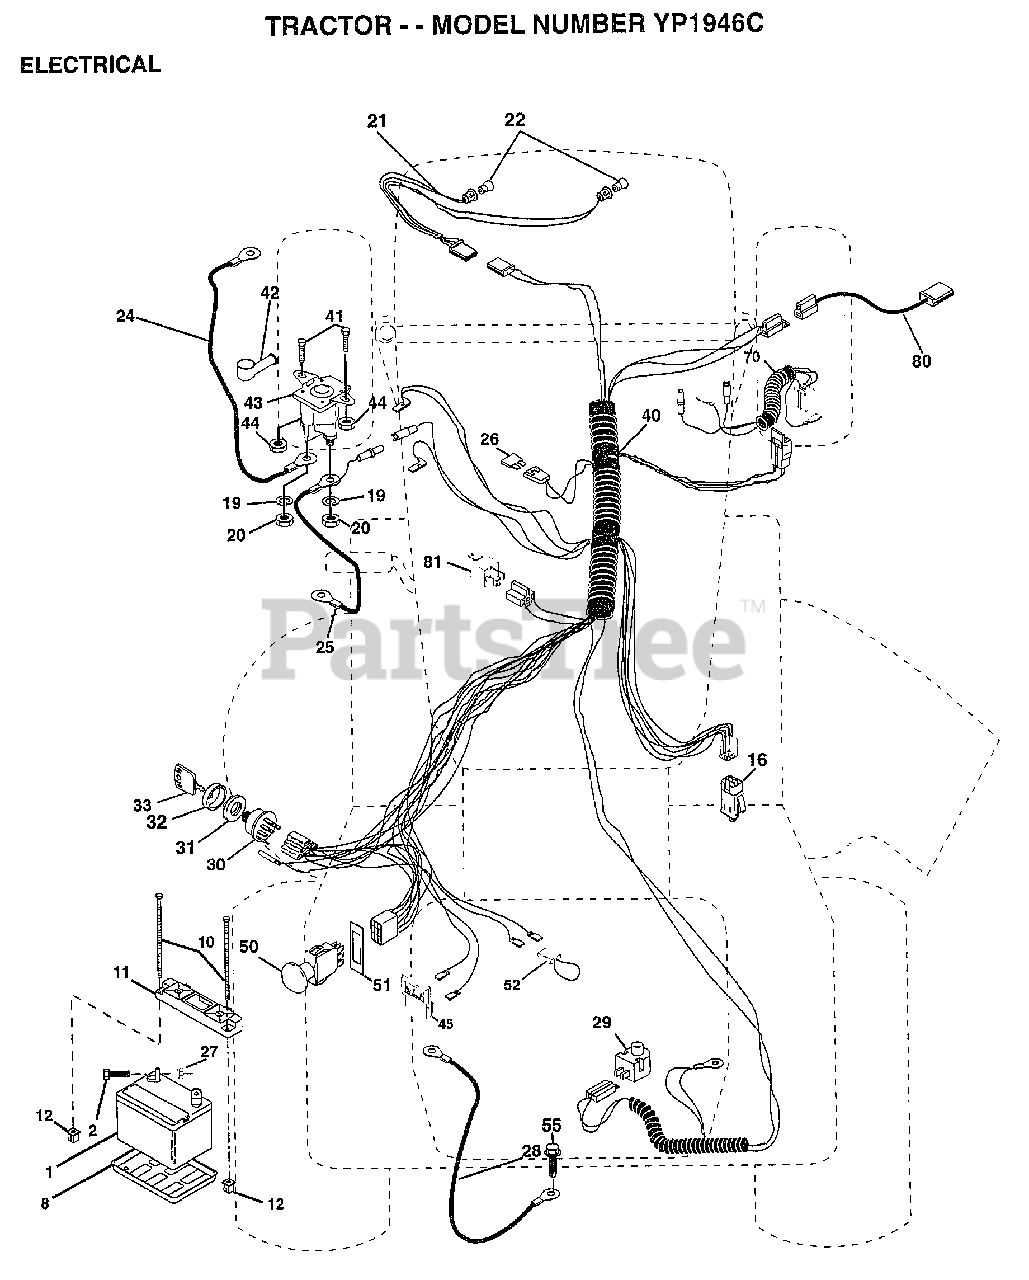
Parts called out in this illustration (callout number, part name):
2	BOLT LT
8	"TRAY T, BATTERY"
11	HOLDDOWN BATTERY
16	SWITCH INTERLOCK
20	NUT
21	HARNESS.ASM.LIGHT W/4152J
22	HEADLAMP BULB
24	"CABLE T, BATTERY"
25	CABLE.6GA.22W/16W
26	FUSE.15 AMP
27	NUT
28	CABLE.GRND.6GA.21
29	SWITCH.PLUNGER
30	SWITCH IGN 4POS
31	NUT IGNITION
32	COVER KEY SWITCH
33	KEY
40	HARNESS.IGNITION
41	BOLT HXHD FIN
44	NUT HXKEP 1/4X20
45	AMMETER
50	PTO SWITCH.BLK
51	RING RETAIN PTO
52	PROTECTION LOOP
55	SCREW LT
70	HARNESS.ENGINE
80	HARNESS.CLUT.EVX.
81	RELAY ASSY T
